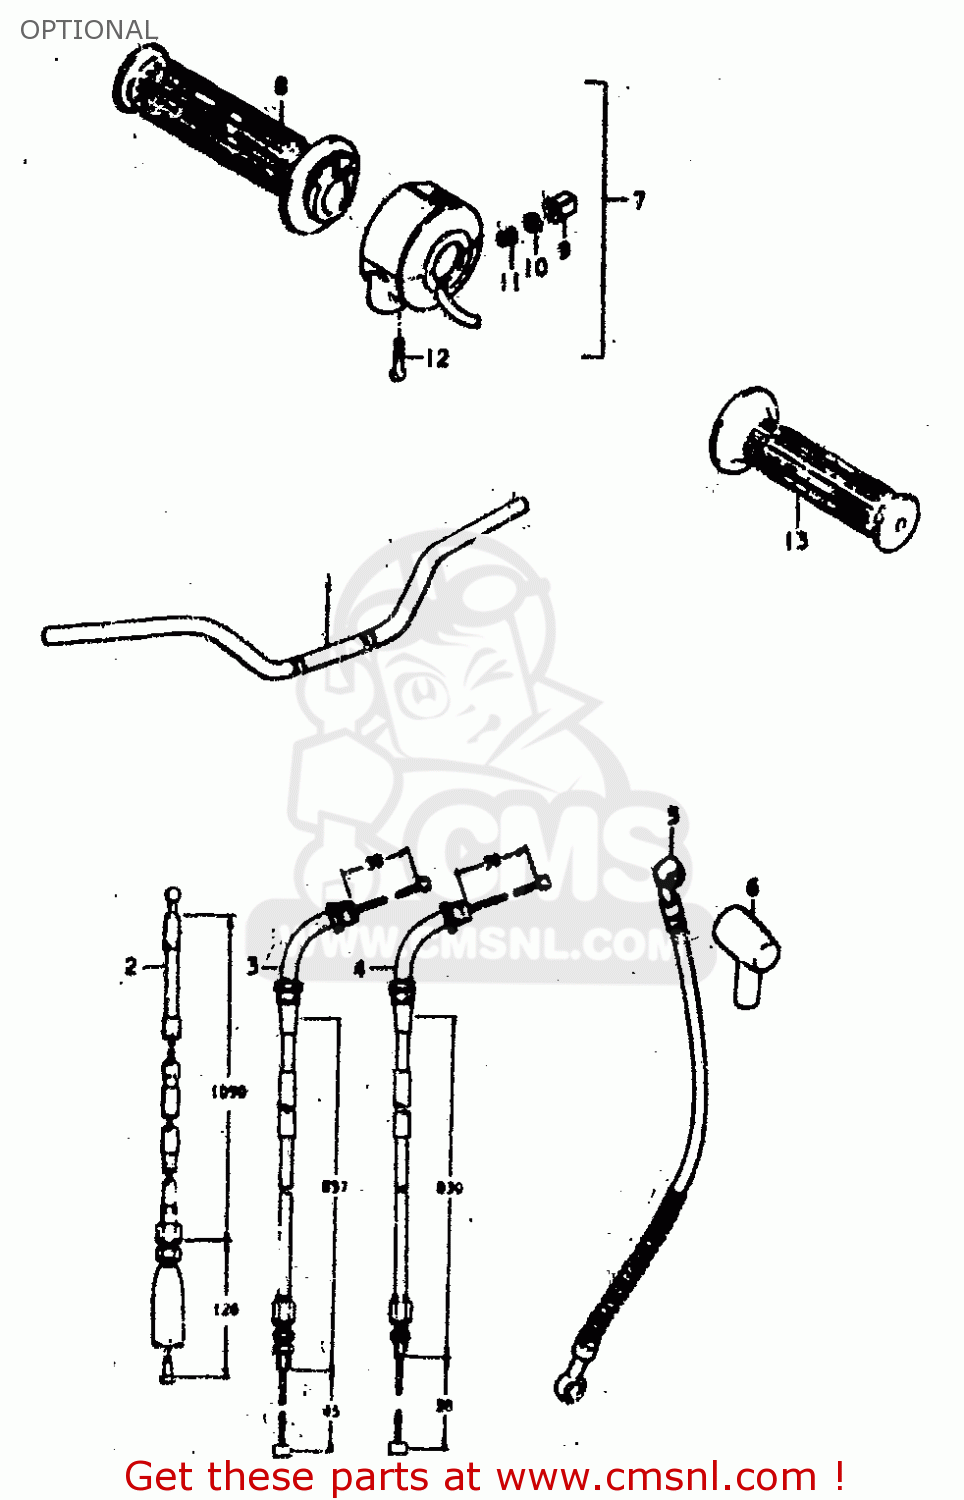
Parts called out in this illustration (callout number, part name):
1	HANDLEBAR
2	CABLE ASSY, CLUTCH
3	CABLE ASSY, THROTTLE (1)
4	CABLE ASSY, THROTTLE (2)
5	HOSE,FRONT BRAKE
6	BOOT
